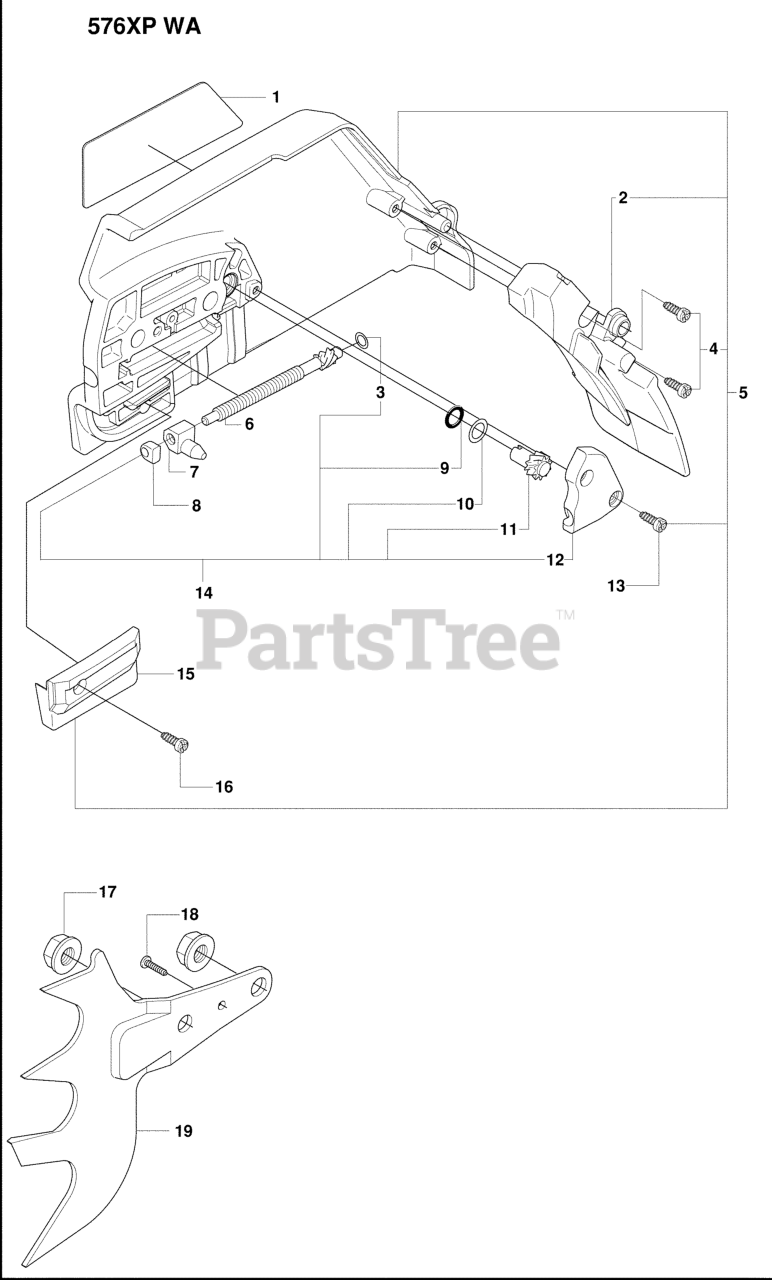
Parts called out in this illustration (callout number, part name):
5	CLUTCH COVER ASSY
6	WORM SCREW / ADJUSTER
11	RP ADJUSTER
14	KIT-CHAIN TENSIONER
15	CHAIN GUIDE
17	NUT M8 FLANGE
19	FELLING DOG
